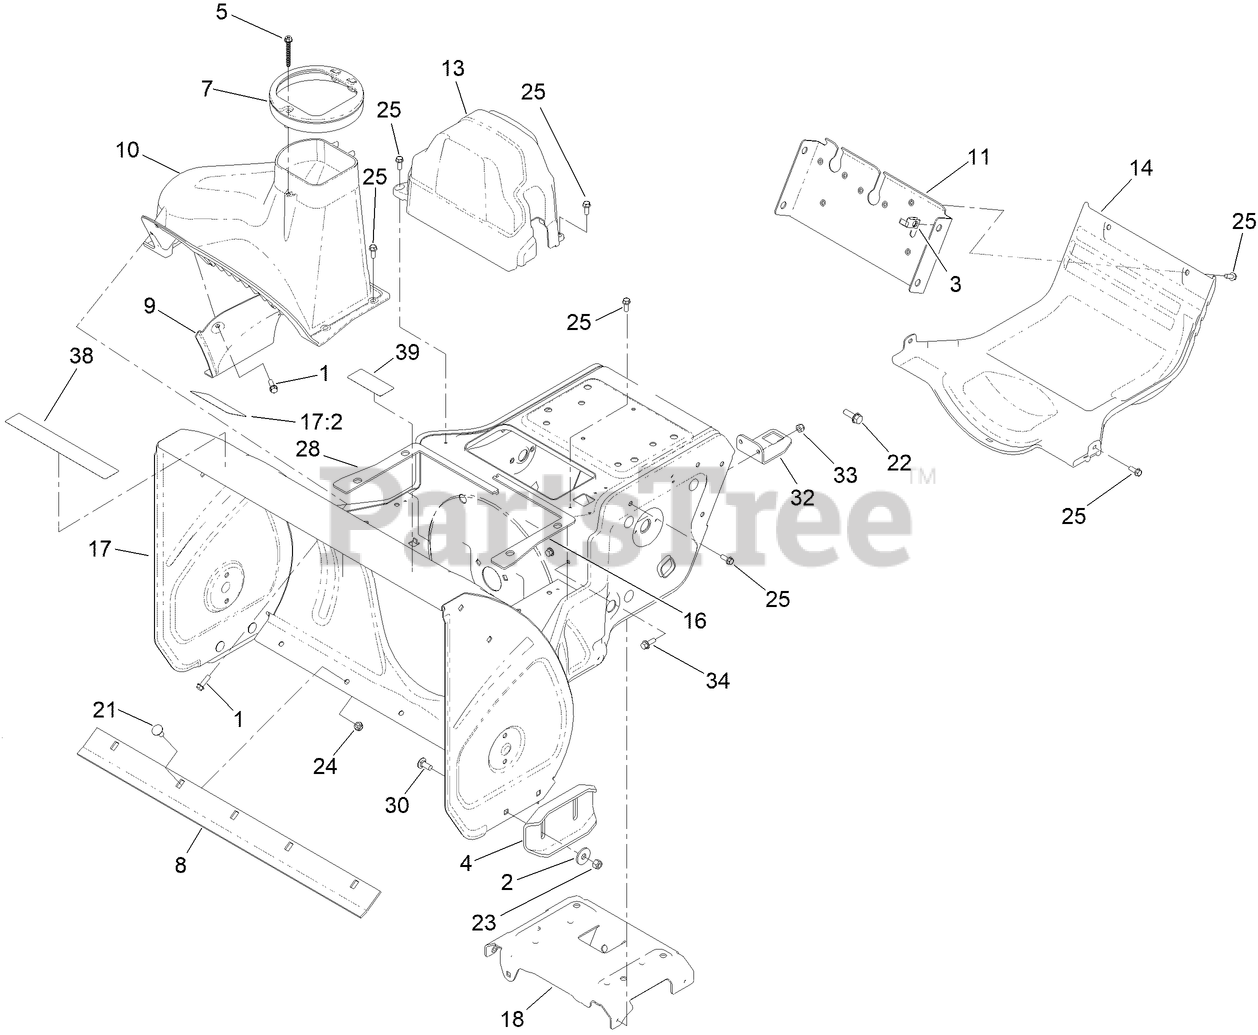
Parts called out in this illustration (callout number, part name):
1	SCREW-HWH
2	WASHER
3	NUT-U
5	SCREW-HWH, PLASTITE
7	GUIDE-CHUTE
8	SCRAPER-24 INCH
9	COVER-LINER
11	BRACE-FRAME
13	COVER-BELT
14	COVER-LOWER
16	SEAL-HOUSING, LH
17	FRAME ASM
17:2	DECAL-DANGER, AUGER
18	BRACE-FRAME
21	SCREW-CARR
22	SCREW-HHF
23	NUT-LOCK, NI
24	NUT-LOCK, NI
25	SCREW-HWH
28	SEAL-HOUSING, RH
30	SCREW-CARR
32	BRACKET-POST, CHUTE
33	SCREW-HHF
34	NUT-HEX
38	DECAL - HARDENED GEARS
39	DECAL - COMPACT 24
